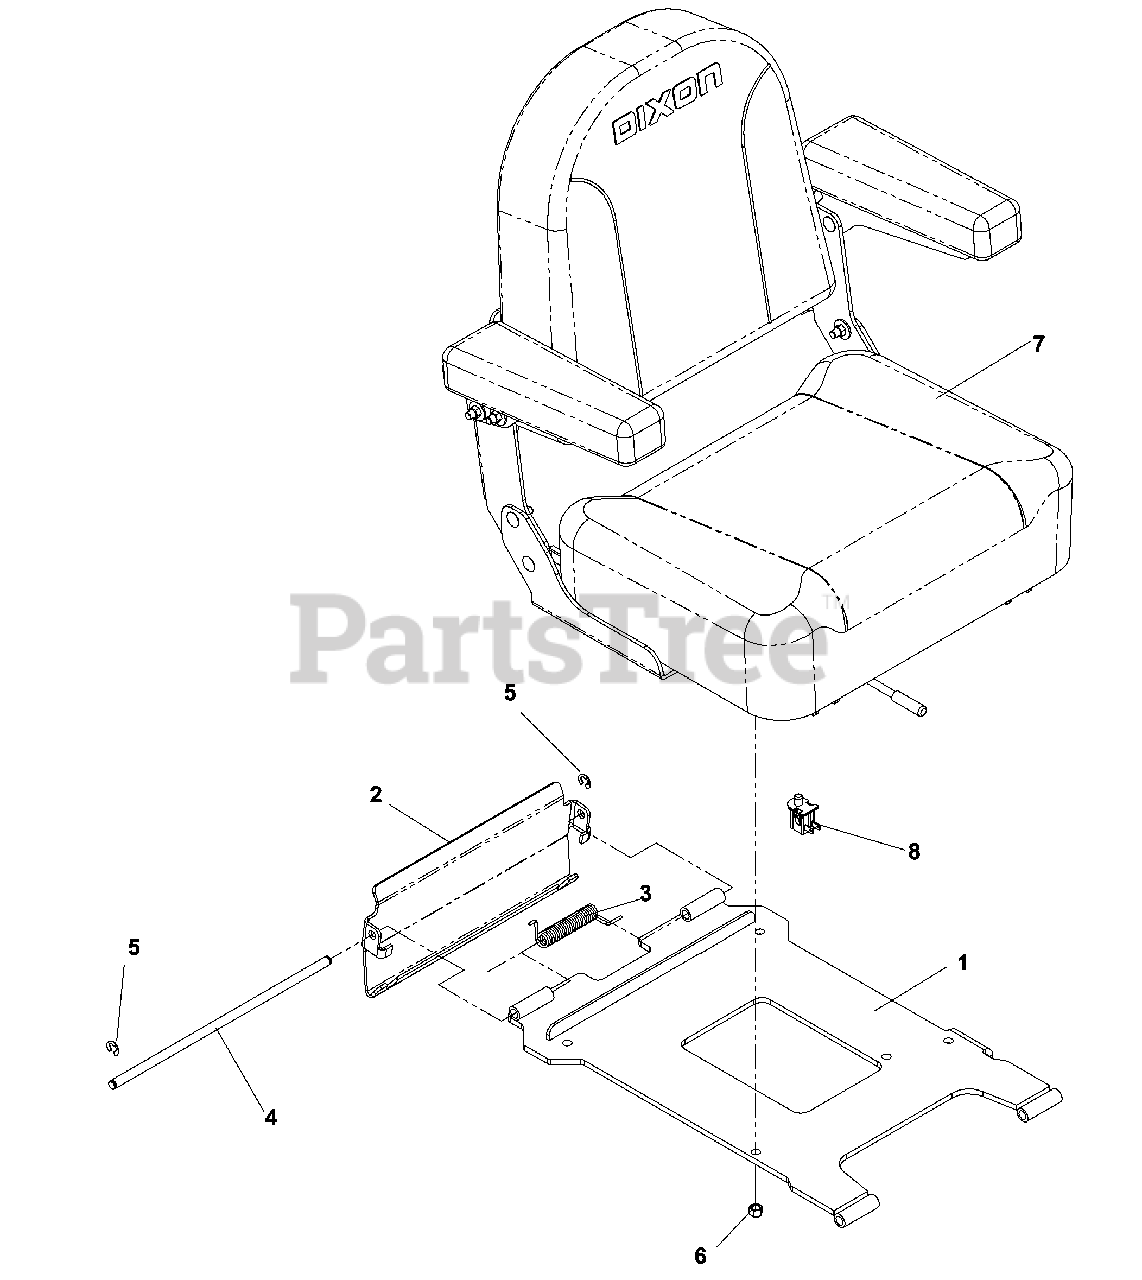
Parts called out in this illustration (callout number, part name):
1	SEAT MOUNT
2	LATCH, SEAT
3	TORSION SPRING (SEAT)
4	SEAT LATCH ROD
5	E RING 3/8"
6	NUT 5/16 NYLOC
7	SEAT ASM W/SLIDE
8	SEAT SWITCH
